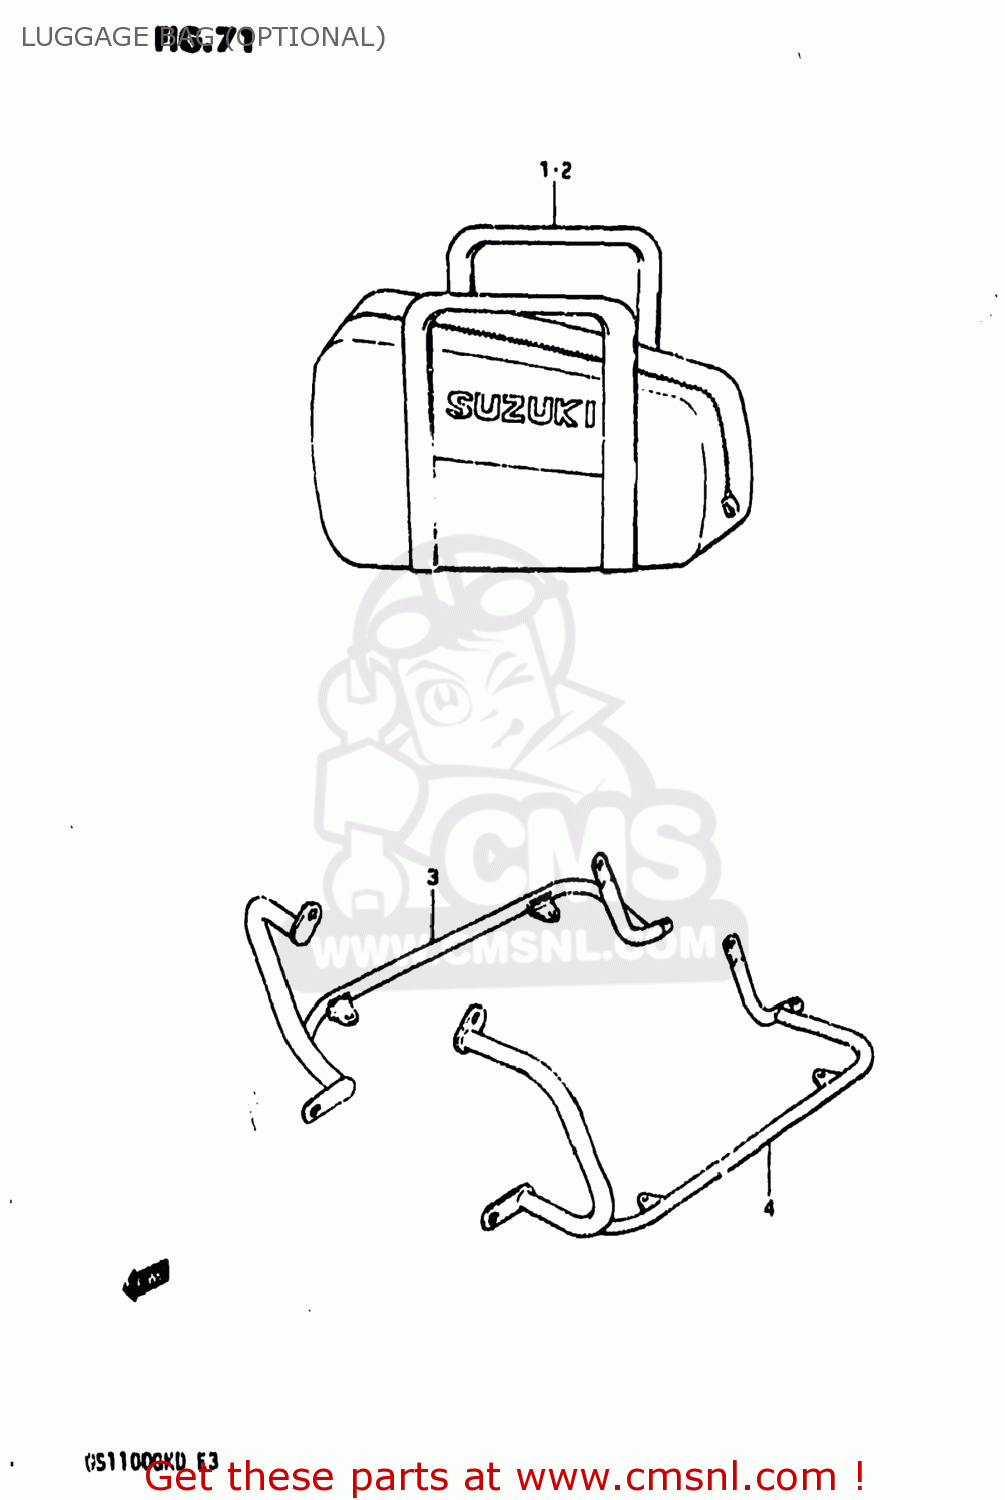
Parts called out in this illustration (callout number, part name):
1	LUGGAGE BAG RH
2	LUGGAGE BAG LH
3	CARRIER,REAR SIDE,RIGHT
4	CARRIER,REAR SIDE,LEFT
